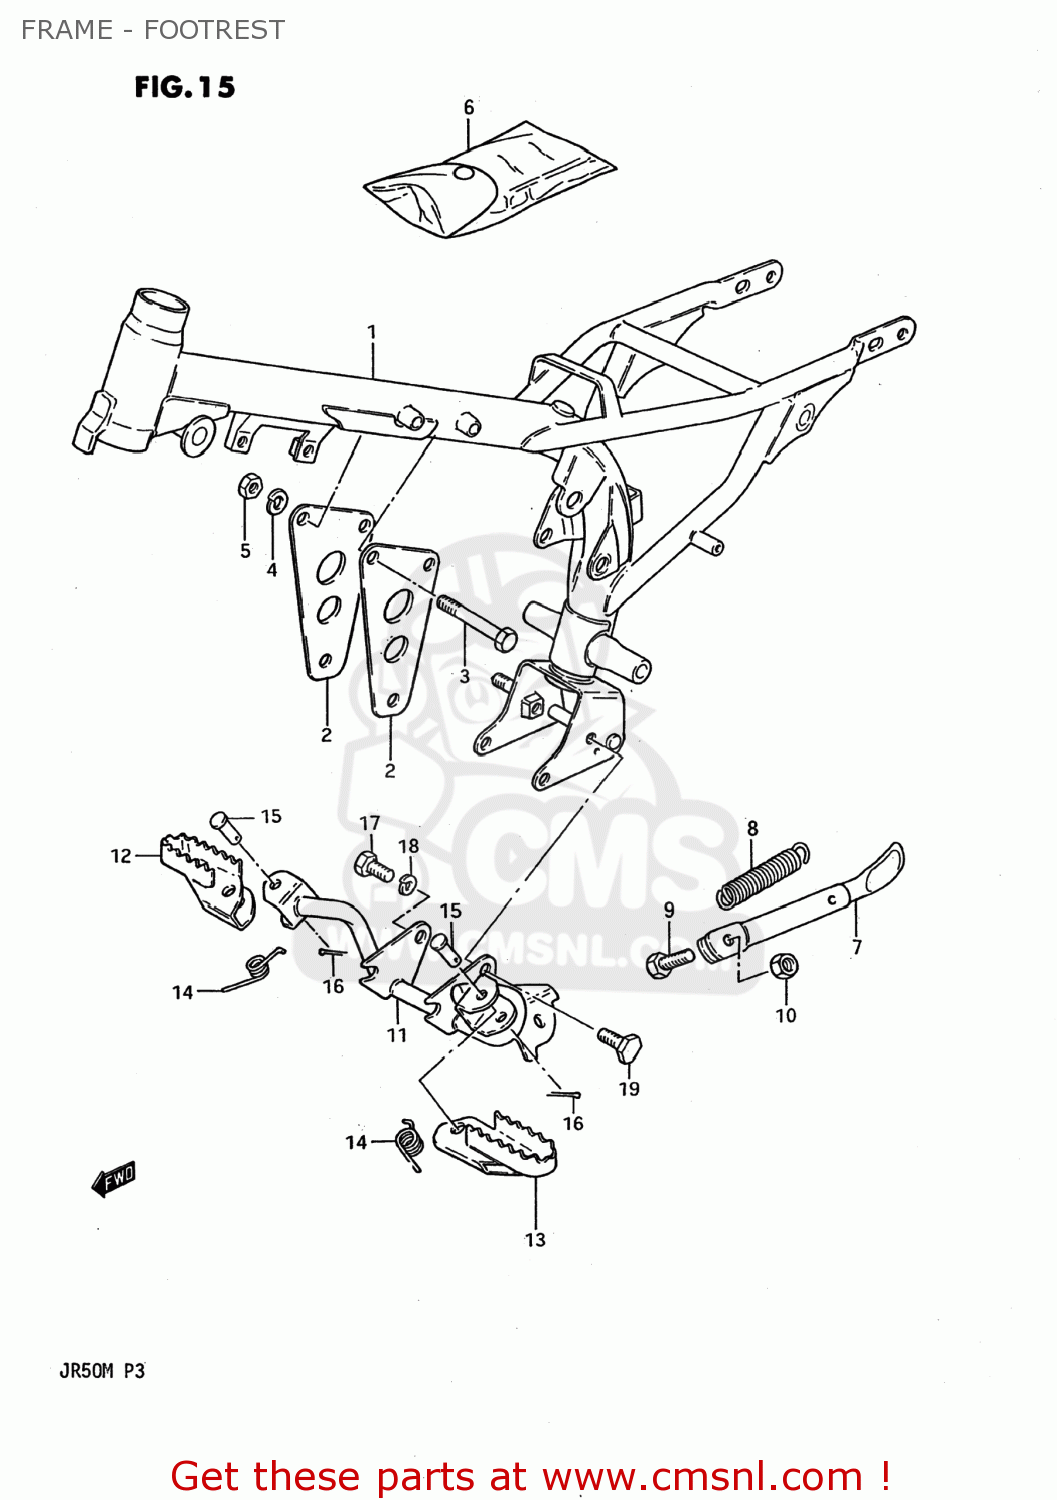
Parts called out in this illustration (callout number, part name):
1	FRAME
2	PLATE,ENG MTG
3	BOLT
4	LOCK WASHER
5	NUT
6	TOOL SET
7	STAND,PROP
8	SPRING
9	BOLT 8X22
10	NUT
11	BAR,FR FOOTREST
12	FOOTREST,FRONT,RIGHT
13	FOOTREST,FRONT,LEFT
14	SPRING
15	PIN
16	PIN 20X20
17	BOLT,8X16
18	LOCK WASHER
19	BOLT(8X14)
